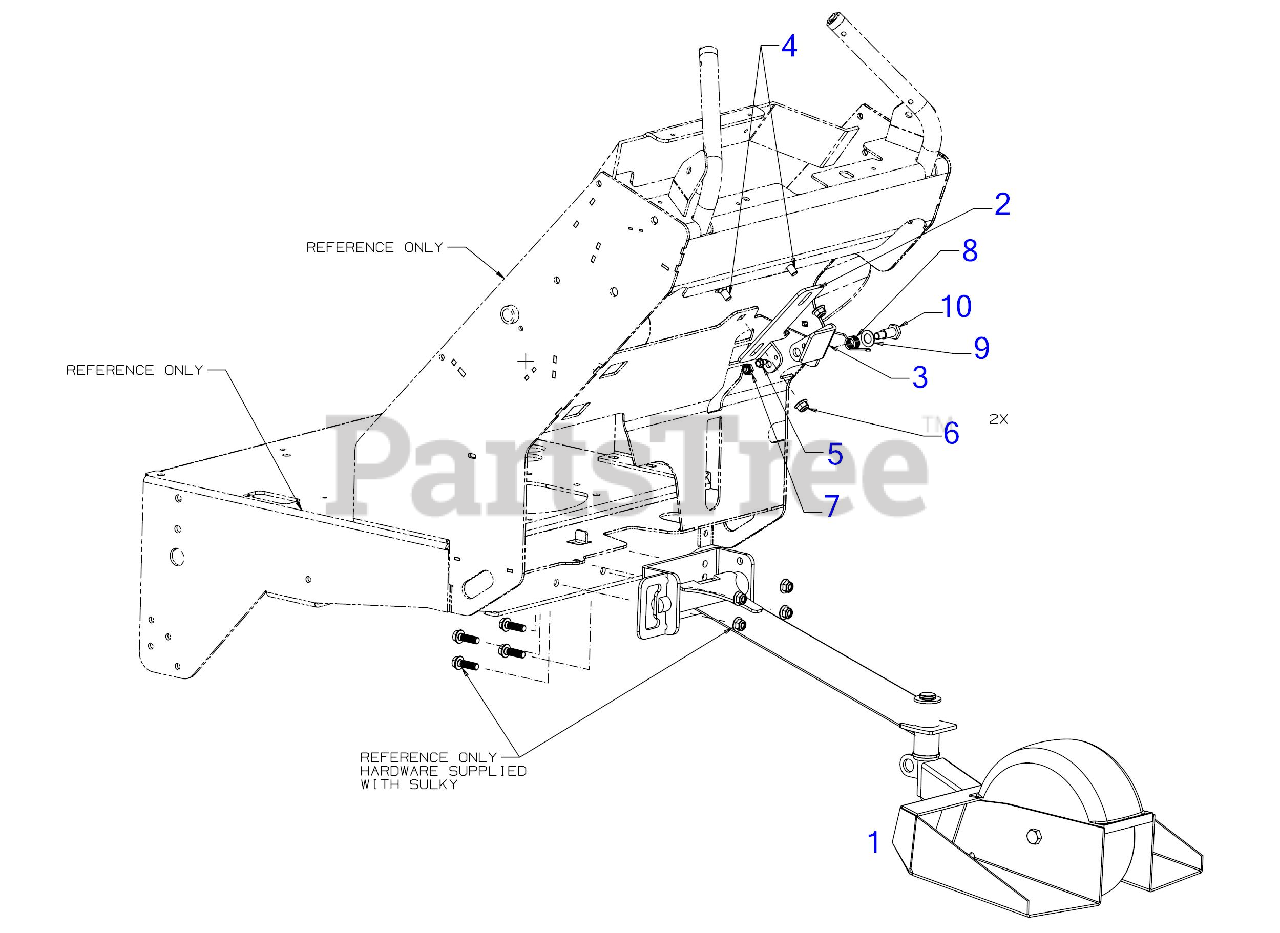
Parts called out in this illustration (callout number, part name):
1	NOT SERVICEABLE
4	CARRIAGE BOLT 3/8-16 x .750 GR5
5	SCREW 1/4-20 X.500
7	TOP LOCK NUT
8	TORSION SPRING
9	FLAT WASHER
10	SHOULDER SCREW .500
